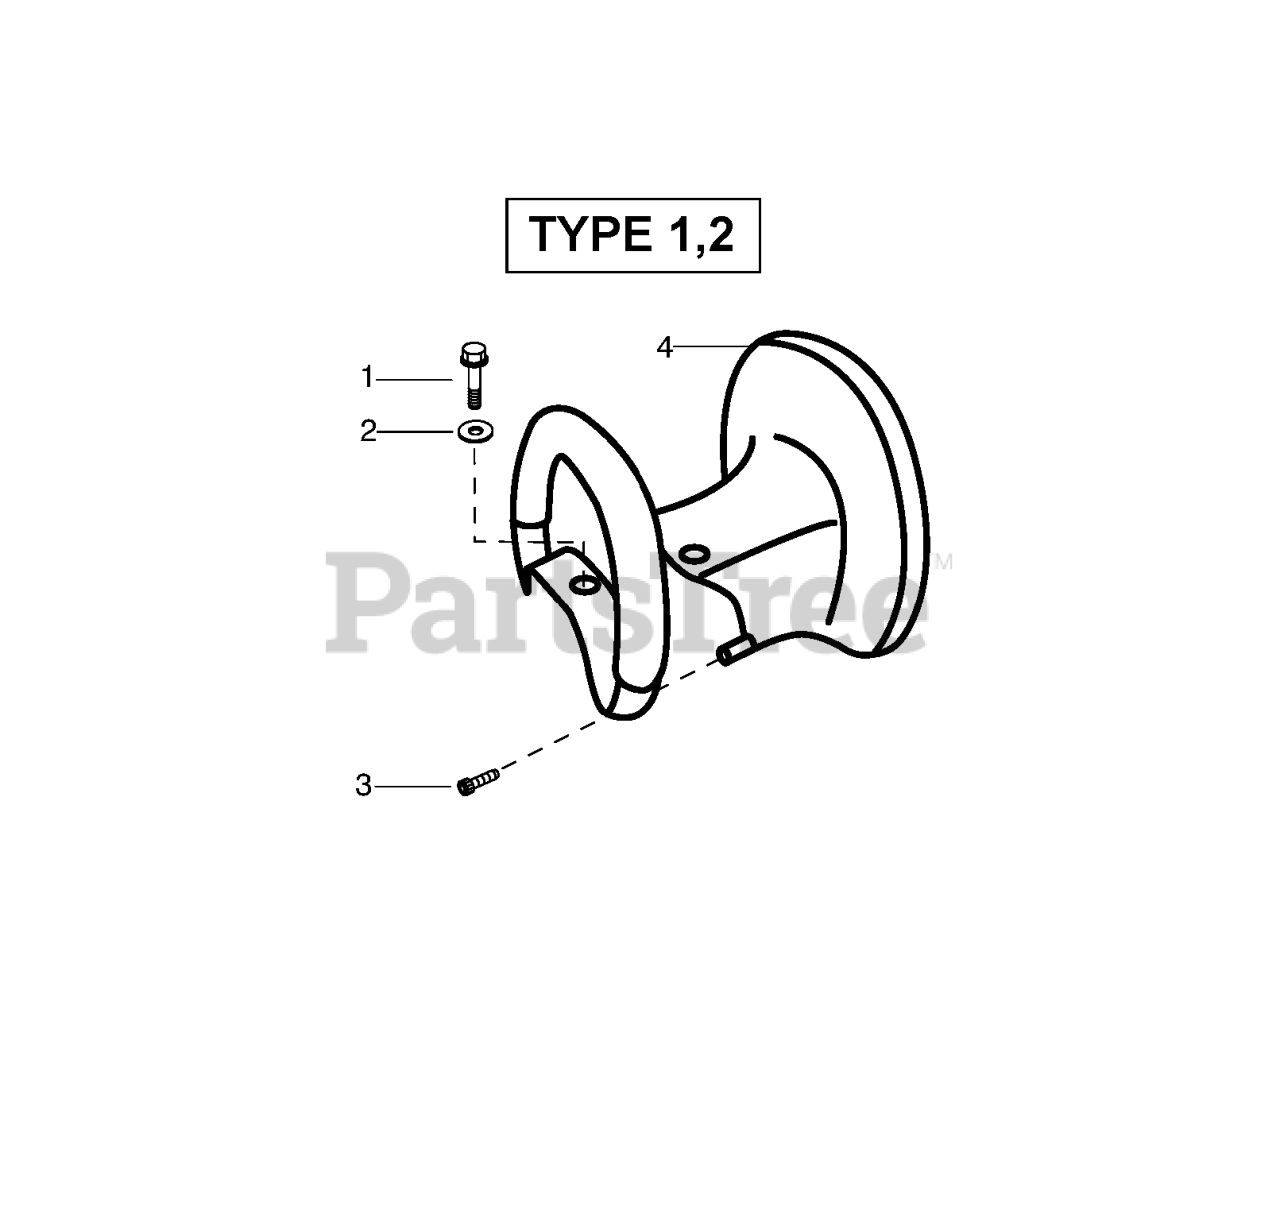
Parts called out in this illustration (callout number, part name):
1	SCREW M6X50
2	WASHER - M6
4	HAND GUARD
